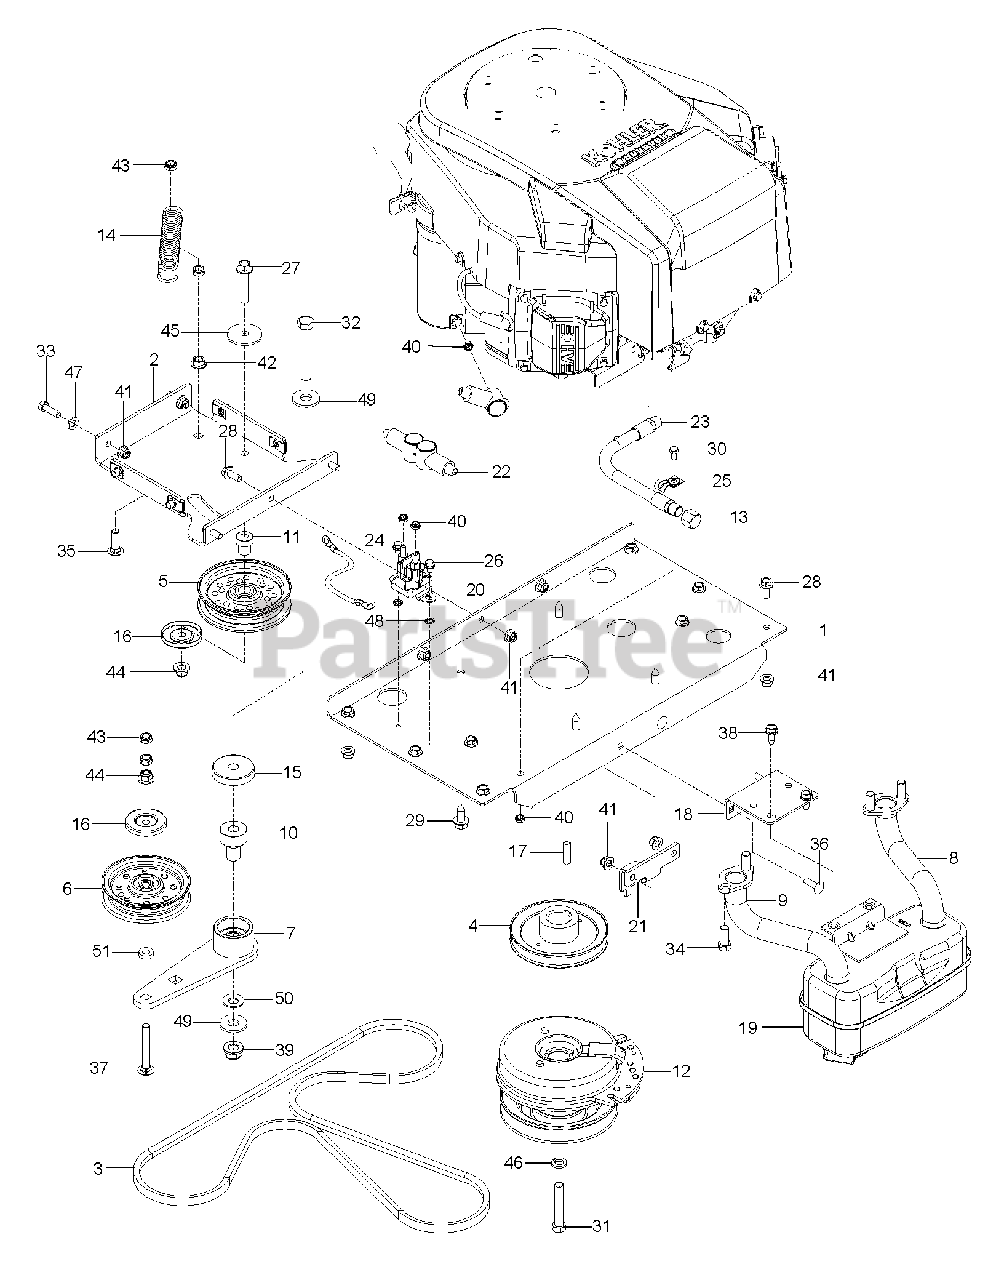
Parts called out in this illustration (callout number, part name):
1	PLATE, ENGINE, BLK
2	PLATE, IDLER, BLK
3	BELT, HYDRO, 3400
4	PULLEY, V, 1.125 BORE
5	IDLER PULLEY
6	FLAT IDLER PULLEY
7	ARM, IDLER, STEEL, W/BGS
8	PIPE.EXHAUST.RH.CV18/20
9	PIPE.EXHAUST.LH.CV18/20
10	PIVOT, BEARING
11	PIVOT, IDLER
12	CLUTCH 200 FT LB
13	U-CLIP 5/16-18 NUT RETAINER
14	SPRING, PUMP
15	SHIELD, DUST
16	DUST SHIELD
17	KEY, 1/4 SQ X 1 1/4
18	BRKT, MUFFLER, BLK
19	MUFFLER ASM TWIN
21	STOP, CLUTCH, BLACK
23	HOSE.ASSEMBLY.OIL.DRAIN
24	CABLE POSITIVE
26	HWST 1/4C X 3/8
27	HHFS 3/8-16 X 2.0 GD 5
28	HHFS 5/16-18 X 3/4
29	HHFS 3/8-16 X 1.0 THD FORMING
30	HCS 1/4-20.
31	CLUTCH BOLT7/16-20X2.5 GR596HR
32	HCS 1/2C X 3 1/4
33	HCS 5/16C X 1
34	HCS 5/16C X 3/4
35	RHSNB 3/8-16 X 1-1/4
36	RHSSNB 5/16C X 1.0
37	RHSNB 3/8-16 X 2.75
38	BOLT 5/16-18 X 3/4
39	NUT, 1/2-13 HEX FLG NYLOC ZD
40	JAM NUT 1/4C (2 2 PW01)
41	5/16-18 NYLOC FLANGE NUT
42	NUT 3/8C WHIZ
43	NUT HEX 3/8-16 NYLON, THIN
44	NUT 3/8-16 HEX FLG NYLOC ZD
45	WASHER, 3/8 SPEC
46	WASHER 7/16 LOCK
47	FLAT WASHER 5/16 SAE
48	WASHER 1/4 INT TOOTH
49	WASH USS FLAT 1/2
50	CONTACT BELLSPR 1/2
51	WASHER 3/8 X 3/4 X .187 TK
